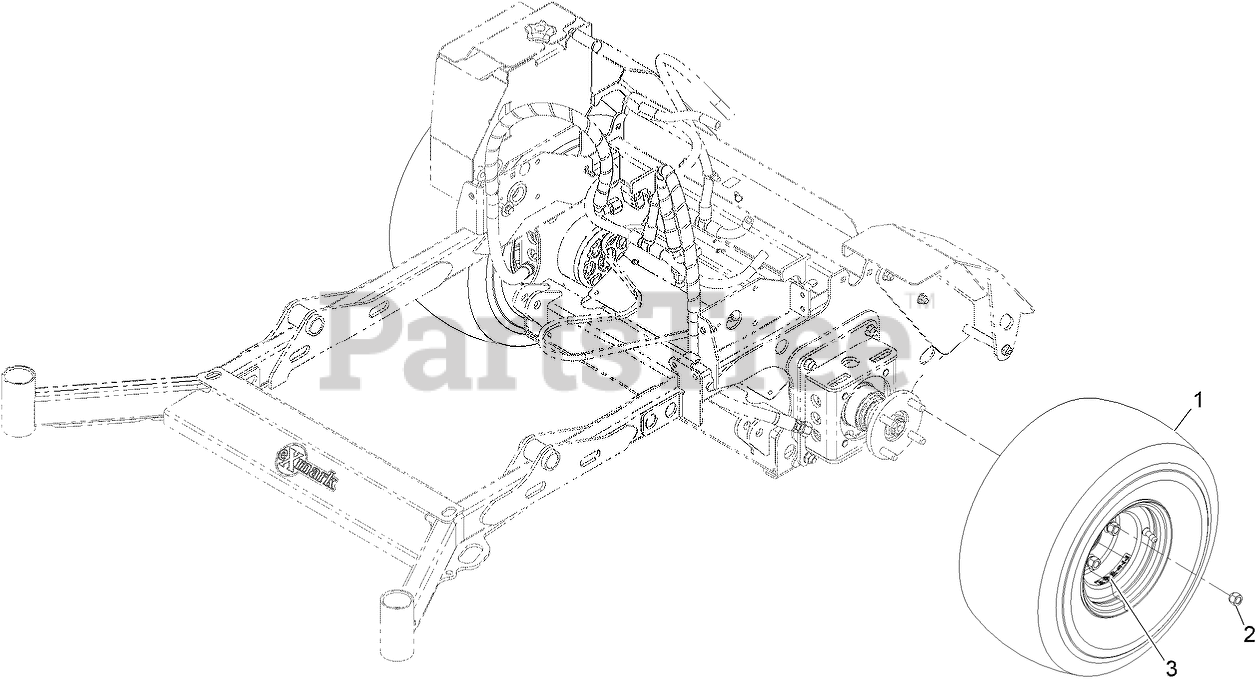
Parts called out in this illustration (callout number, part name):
1	Wheel/Tire ASM
2	NUT-LUG
3	DECAL-TORQUE, WHEEL HUB LUG
